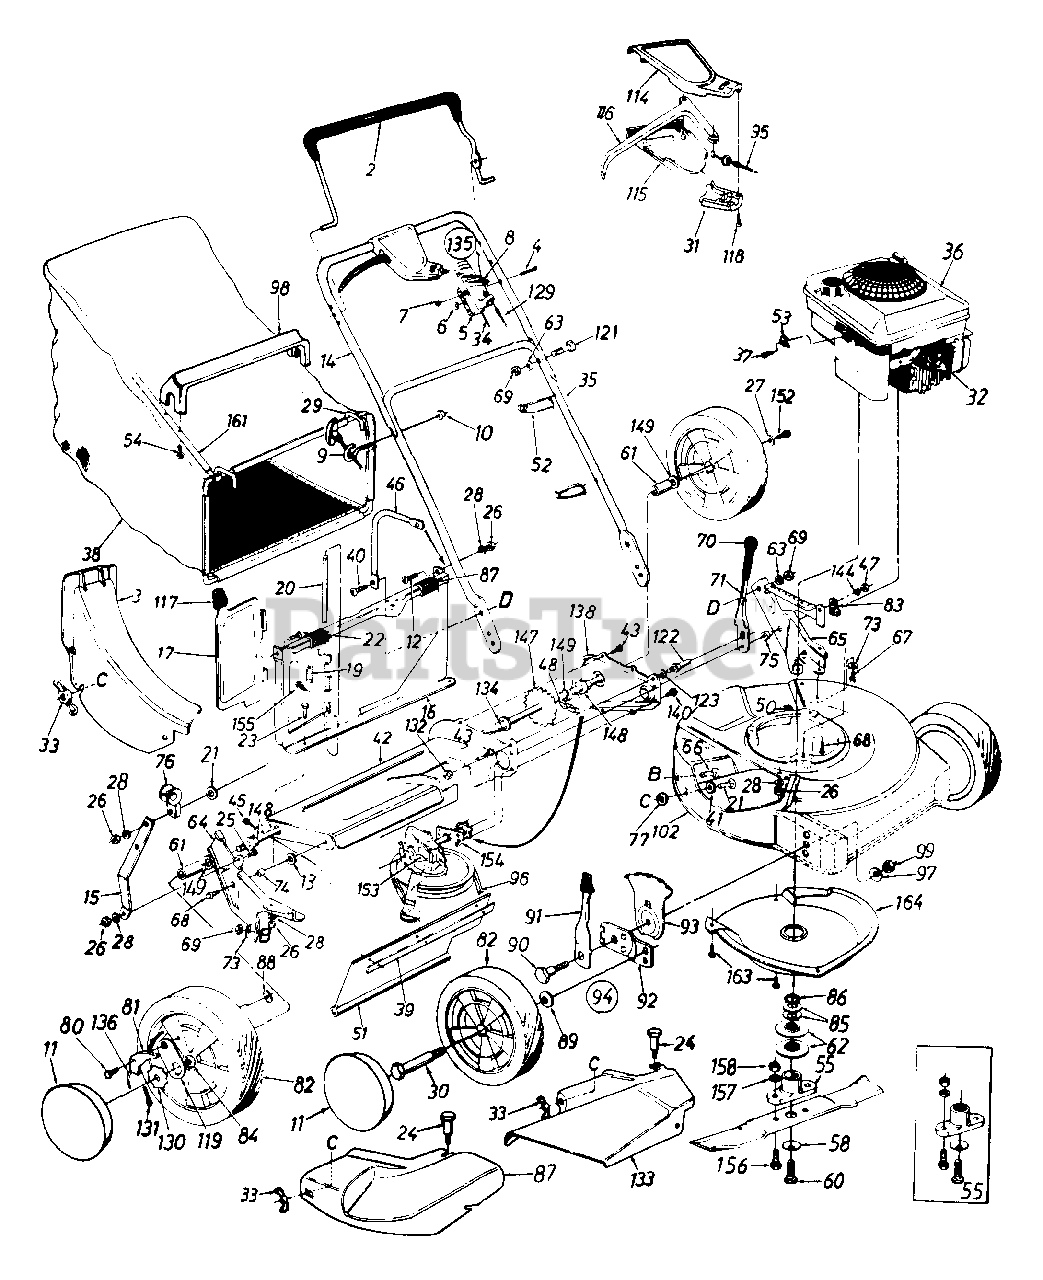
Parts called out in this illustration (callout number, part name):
2	Control Handle Ass'y.- L.H.
3	Rear Discharge Chute Ass'y.
4	Oval C-Sunk Scr.
5	Throttle Body
6	Spr. Wash..66" I.D.
7	Hex L-Nut 1/4-20 Thd.
8	Throttle Lever
9	Rope Guide
10	Hex L-Nut 1/4-20 Thd.
11	Hub Cap
12	Truss Mach, Scr. 1/4-20 x .62"
13	Fl-Wash..383" I.D. x 1" O.D.
14	Upper Handle - Painted
19	Torsion Spring
20	Pivot Pin
21	Carriage Bolt 1/4-20 x .62"
22	Truss Mach. Scr. 1/4-20 x 3/4"
23	Hex Bolt 1/4-20 x .50" Lg.
24	Shoulder Bolt .312 Dia. x .18 Lg.
25	Hex Bolt 1/4-20 x .62" Lg.
26	Hex Nut 1/4-20 Thd.
27	Bell-Wash. 1/4" 1.0.
28	L-Wash. 1/4" I.D.
30	Axle Bolt
31	S.P. Control Cover
32	Spark Plug Insulator
33	Wing Nut w/Washer
34	Throttle Control Wire 61"
35	Lower Handle - Painted
37	Hex Self-Tap Scr. #10-32 x .62"
38	Grass Bag
39	Retaining Strip
40	Truss Mach. Scr. 5/16-18 x .75"
41	Fl-Wash..344" I.D. x .62"
45	Hex AB-Tap Scr. 1/4 x .62"
46	Catcher Panel Support Arm
47	Hex Patch L-Nut 3/8-24 Thd.
48	#48 Chain .500" Pitch x 30 Links
51	Rear Flap 3.75" x 17.30" Lg.
52	Cable Tie
53	Cable Clamp
54	Hex AB Scr. #12 x 1.25" Lg.
55	Blade Adapter Kit
58	Bell-Wash..39" I.D.
60	Hex Bolt 3/8-24 x 1.5" Lg. (Grade 5)
61	Spacer .513" I.D. x .703" O.D. x 69" Lg.
62	Lower Pulley Half
63	L-Wash. 5/16" I.D.
64	R.H. Handle Wheel Brkt. Ass'y.
65	L.H. Handle Wheel Brkt. Ass'y.
66	Carriage Bolt 5/16-18 x .62"
67	Hex Wash. Hd. B-Tap Scr. 5/16-18
68	Hex Wash. Hd. TT-Tap Scr. 3/8-16
69	Hex Nut 5/16-18 Thd.
71	Height Adj. Lever
73	Bell-Wash. 5/16" I.D.
74	Spacer
75	Shld. Spacer .500" Dia.
76	Rope Guide
77	Bolt Retainer 1/4 x .50" O.D.
80	Shld. Scr..342" Dia. x .268
81	Pawl
82	Wheel Ass'y. Comp.
83	Clamp
84	Upper Pulley Half
85	Bell-Washer 7/8" I.D.
86	Crankshaft Spacer
87	Panel Clip
88	Weld L-Nut 1/4-20 Thd.
89	Bell-Wash..4" I.D. x .88" O.D.
90	Shld. Bolt .5" Dia. x .434"
91	Spring Lever Ass'y. w/Knob
93	Height Adj. Plate
94	Front Height Adj. Ass'y. Comp.- R.H.
95	S.P. Cable
96	"V"-Belt
97	Bell-Wash..39" I.D. x 1.38" O.D.
98	Bag Handle
99	Hex Nut 3/8-16 Thd.
115	Self-Propelled Control Cover
117	Door Grip
118	Fl-"C"-Sunk Hd. Tap Scr. #10 x .75" Lg.
119	Pawl Plate
121	Curved Carr. Bolt 5/16-18 x 1.38" Lg.
122	Shld. Pin 3/8-24 x 1.43" Lg.
123	L-Wash. 3/8" I.D.
129	Control Cable 47" Lg.
130	Ratchet Wheel 1.62" O.D.
131	Cotter Pin 1/8" Dia. x 1.00" Lg.
132	Hex Jam Nut 3/8-24 Thd.
133	Side Chute Deflector Ass'y.
134	Hex Flange Bearing
135	Throttle Box Comp.
136	Spring - Nylon
144	Fl-Wash..385" I.D. x .87"
147	Rear Shaft Ass'y. 21.94" Lg.
148	Hex Flange Bearing .506" I.D. Plastic
149	Fl-Wash..531" I.D. x .930"
152	Hex Bolt 1/4-20 x .62" Lg. (Grade 5)
153	Transmission Comp. (See Breakdown)
155	Hex B-Tap Scr. 410 x .38
156	Hex Scr. 3/8-24 x 1.0" Lg.
157	L-Wash. 3/8" I.D.
158	Hex Nut 3/8-24 Thd.
163	Hex Wash. Hd. Tap Scr. 1/4 x .5" Lg.
164	Mulching Baffle
